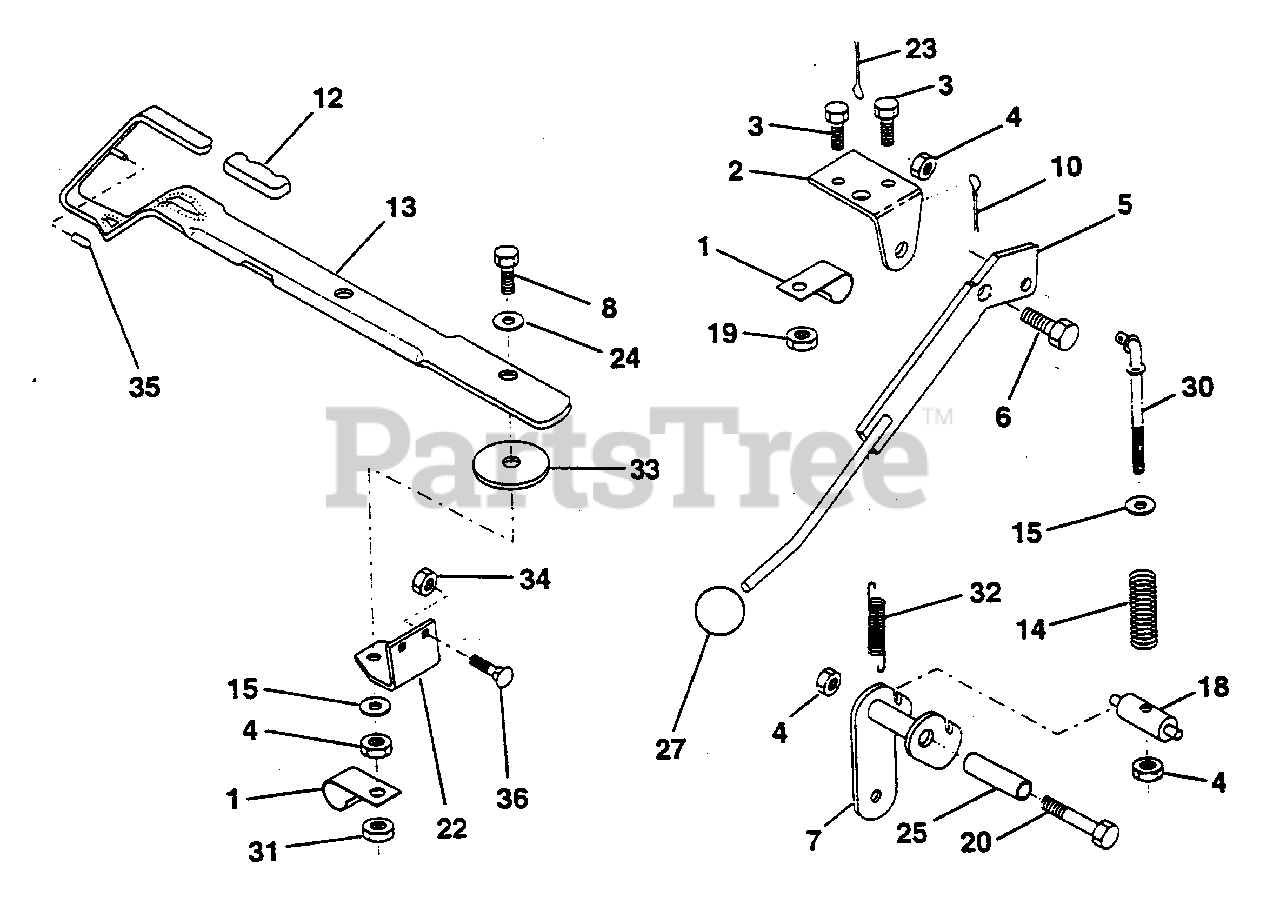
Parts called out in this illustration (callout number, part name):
1	Clip, Insulated (AYP part number)
2	Bracket, Mower Clutch (AYP part number)
3	Bolt, Hex Head, Fin. 1/4-20 UNC x 1/2 Grade 5 (AYP part number)
4	Nut, Crownlock 3/8-16 UNC
5	Assembly, Clutch Lever (AYP part number)
6	Bolt, Shoulder (AYP part number)
7	Assembly, Mower Clutch Arm (AYP part number)
8	Bolt, Hex Head 3/8-16 UNC x 1-1/2 (AYP part number)
10	Pin, Cotter 1/8 x 3/4 (AYP part number)
12	Handle, Lift Lever (AYP part number)
13	Assembly, Lift Handle (AYP part number)
14	Spring, Compression (AYP part number)
15	Washer 13/32 x 1 x 11 Gauge (AYP part number)
18	Trunnion, Threaded 3/8-16 (AYP part number)
19	Nut, Crownlock 1/4-20 (AYP part number)
20	Bolt, Hex Head, Fin. 3/8-16 UNC x 2-3/4 (AYP part number)
22	Bracket, Lift Lever (AYP part number)
23	Pin, Cotter 3/32 x 3/4 (AYP part number)
24	Washer 25/64 x 1-1/4 x 12 Gauge (AYP part number)
25	Tube, Spacer (AYP part number)
27	Knob (AYP part number)
30	Rod, Tension, Clutch (AYP part number)
31	Nut, Centerlock (AYP part number)
32	Spring, Extension, Return (AYP part number)
33	Washer 13/32 x 2-3/8 x 8 Gauge (AYP part number)
34	Nut, Crownlock 5/16-18
35	Cap, Vinyl, Red (AYP part number)
36	Bolt, Carriage 5/16-18 x 3/4
